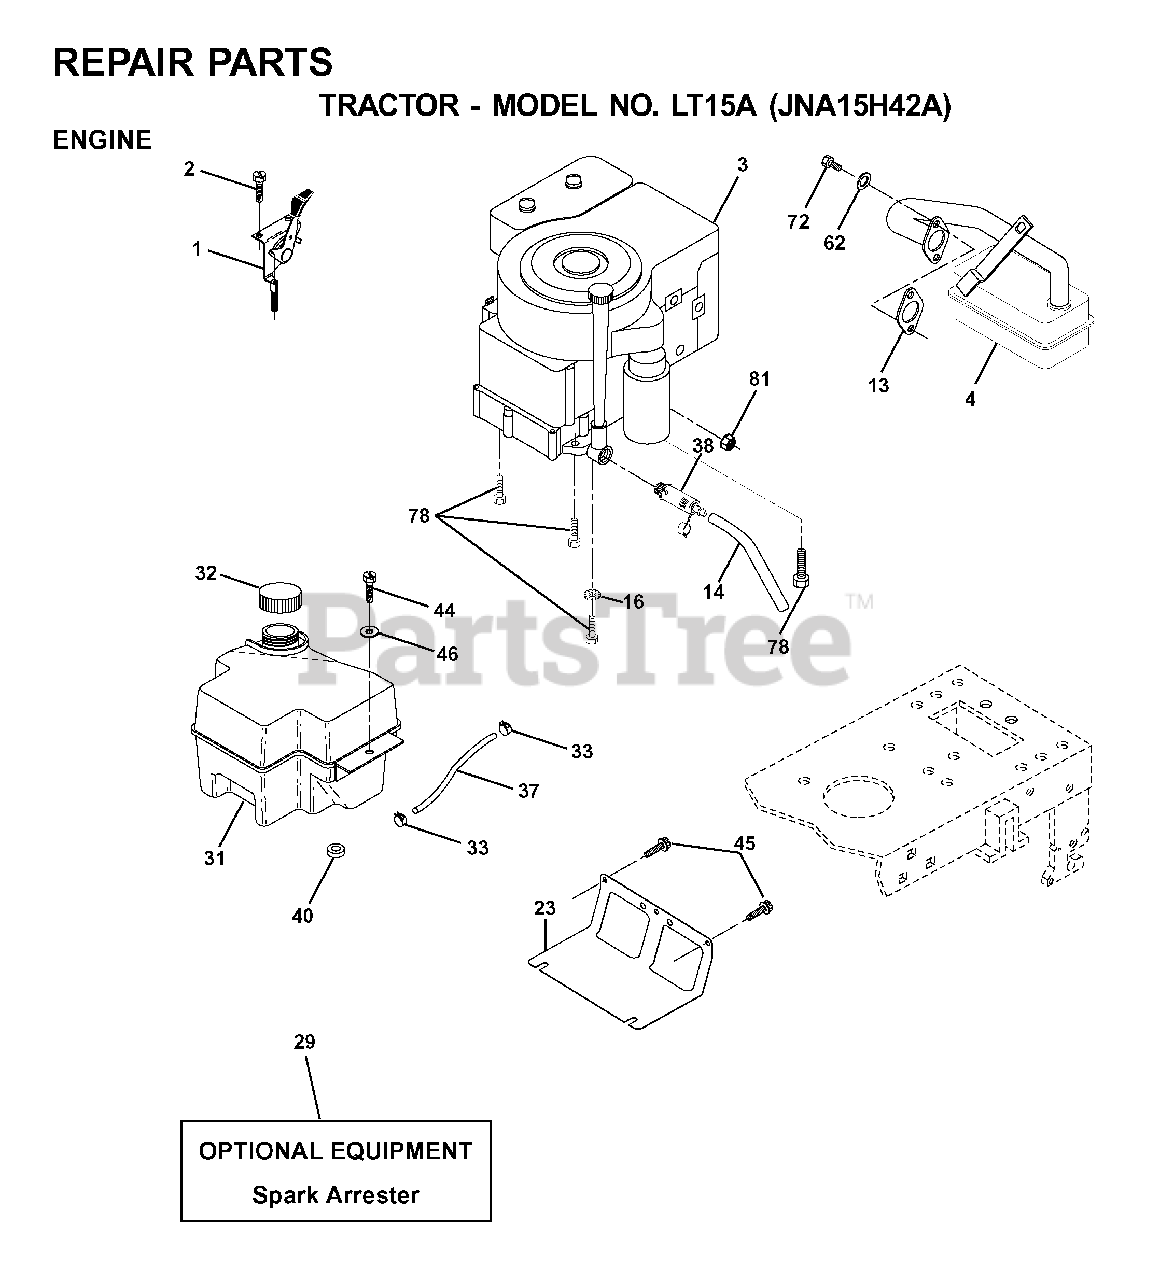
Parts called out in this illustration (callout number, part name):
1	CONTROL TH/CH FLAG
2	SCREW LT
13	REPL BY 532 27 22-93
14	TUBE, DRAIN OIL ASM.
16	LOCKWASHER
23	SHEILD.BROWNING.DBR.GUARD
29	ARRESTER SPARK (OPTIONAL)
31	TANK, 2GAL
32	FUEL CAP
33	HOSE CLAMP
37	LINE.FUEL.20
38	PLUG, OIL DRAIN EASY
40	GROMMET T
44	SCREW HEXWSHR 1/4-20X3/4
45	SCREW, 3/8-16X3/4
62	LOCKWASHER
72	SCREW
78	SCREW.3/8-16
81	NUT
